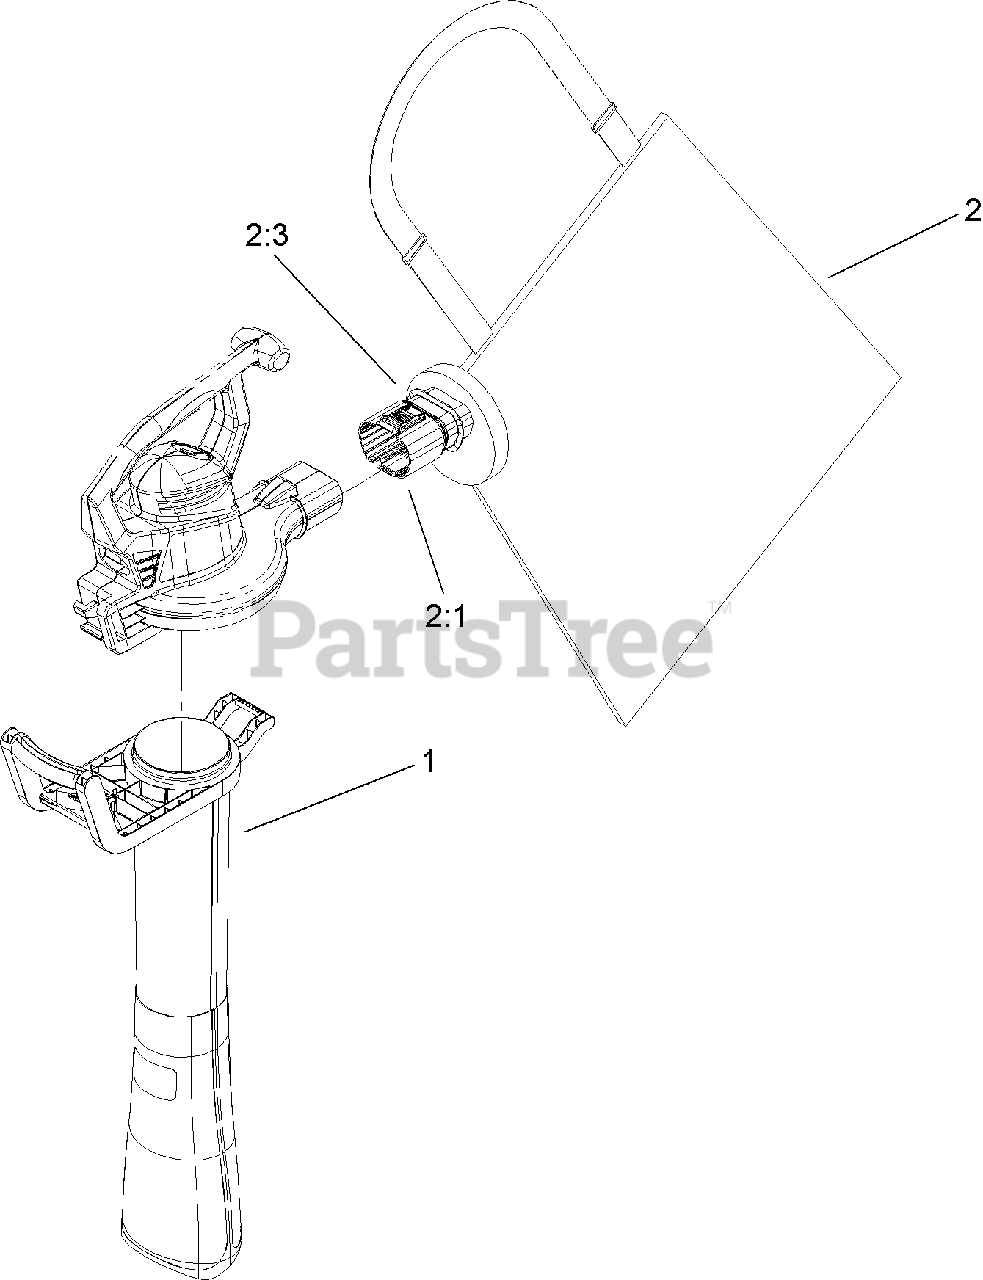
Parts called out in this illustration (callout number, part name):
1	Vac Tube ASM
2	BAG ASM
2:1	COLLAR-BAG
2:3	TIE-CABLE
